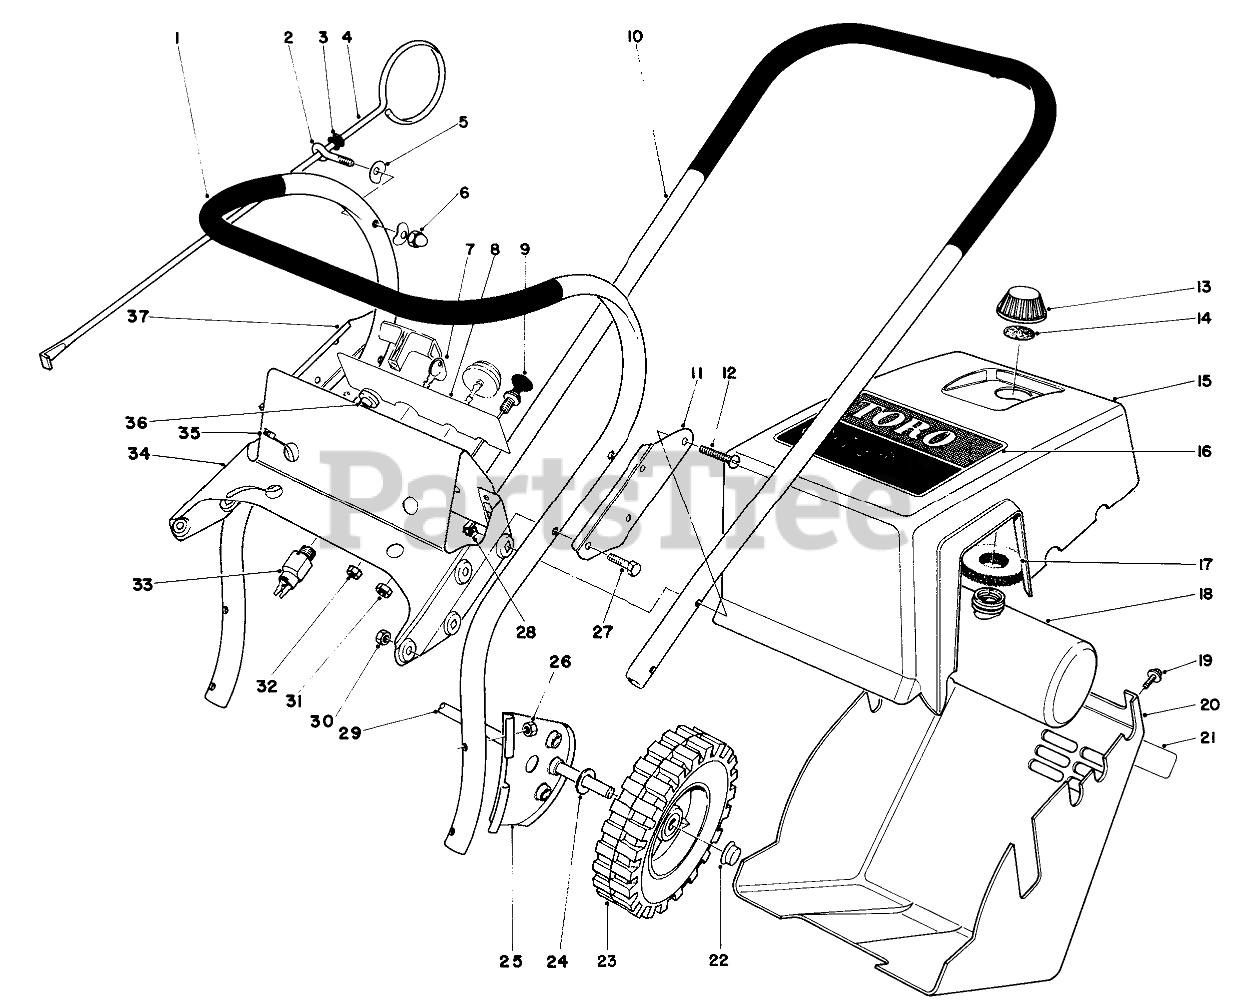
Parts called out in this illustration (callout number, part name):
1	LOWER HANDLE
2	Bolt-Eye
3	GROMMET
4	Vane Adj. Rod
5	WASHER
6	NUT-CAP
7	Key
8	CONTROL PANEL DECAL
9	CHOKE CONTROL
10	Upper Handle
11	SPLICE PLATE
12	Sems Mach. Screw
13	Gas Cap Assy. (Incl. Ref. #14)
14	GAS CAP GASKET
15	Shroud (Incl. Ref. #16)
16	Decal-Toro
17	FOAM PAD
18	Gas Tank Assembly (Incl. Ref. #13 & 14)
19	SCREW
20	Lower Shroud (Incl. Ref. #21)
21	Decal-Instruction
22	RETAINER-PUSH ON
23	WHEEL
24	WASHER-FLAT
25	WHEEL BRKT B
26	NUT-HEX
27	SCREW-HH
28	Nut Retainer
30	NUT-LOCK, CONE
31	PAL NUT/CHOKE CNTRL
32	NUT-KEPS
33	SWITCH-ON / OFF
34	Tank Support & Control Panel (Incl. Ref. #8)
35	Strap
36	GUIDE-ROPE, STARTER
37	Plate-Splice
